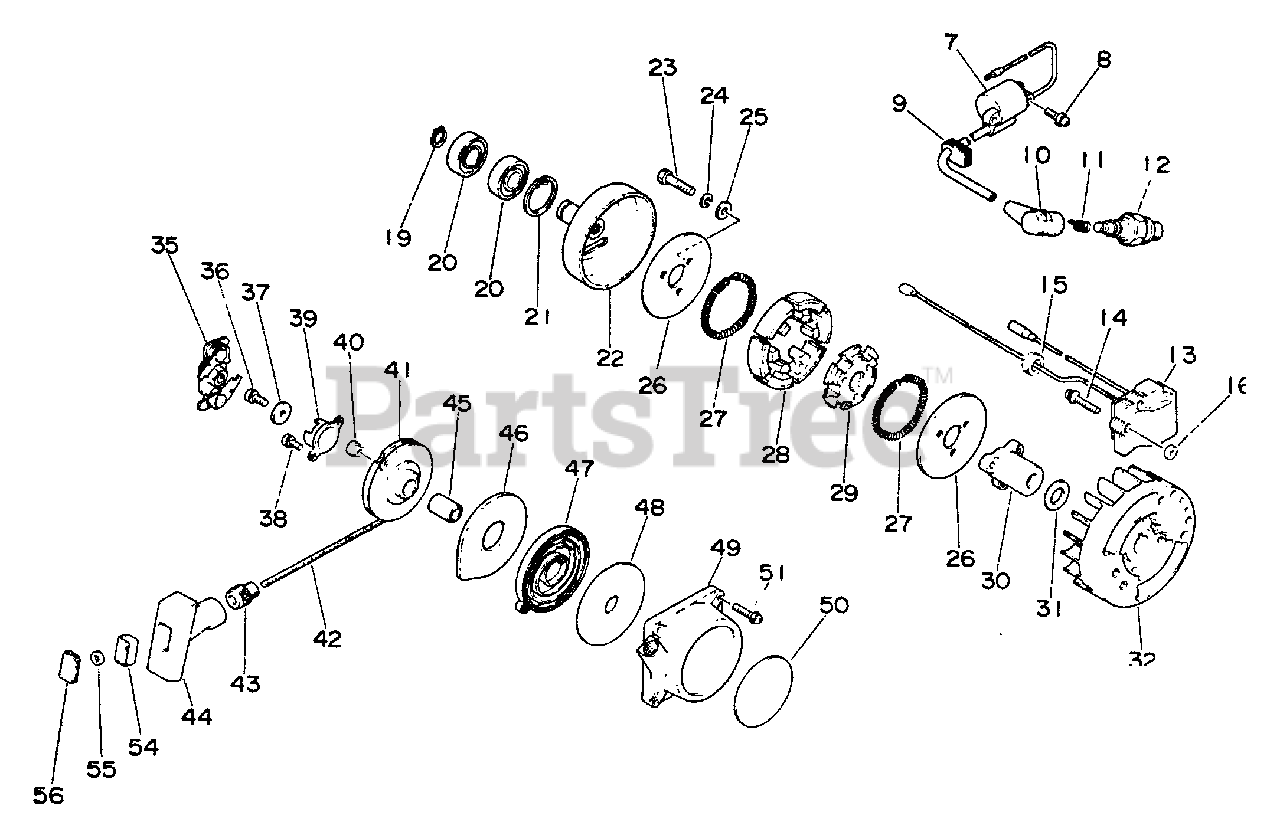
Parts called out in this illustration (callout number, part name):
7	COIL, IGNITION
8	SCREW - 4X14
10	CAP, SPARK PLUG
11	TERMINAL, SPARK PLUG CAP
12	SPARK PLUG -- BPM-7A
13	COIL, IGNITION
14	SCREW - 4X22
19	RING, RETAINING - 15
20	BEARING, BALL - 6203
21	RING, RETAINING - 35
22	DRUM, CLUTCH
23	BOLT - 5X25
24	LOCKWASHER - 5
25	WASHER - 5
26	PLATE, CLUTCH
26	CLUTCH ASSY
27	SPRING, CLUTCH
28	SHOE, CLUTCH
29	HUB, CLUTCH
30	ADAPTOR
31	WASHER
32	FLYWHEEL
35	STARTER PAWL ASSY
36	SCREW - 5X10
37	WASHER - 5
38	SCREW - 4X8
39	CATCHER, PAWL
40	RETAINER, ROPE
41	REEL, ROPE
42	ROPE, STARTER - 3.5X850
43	GUIDE, ROPE
44	GRIP, STARTER
46	PLATE, STARTER
47	SPRING, REWIND
48	PLATE, STARTER
49	CASE, STARTER
50	LABEL - ECHO
51	SCREW - 4X20
54	RING, RETAINING
